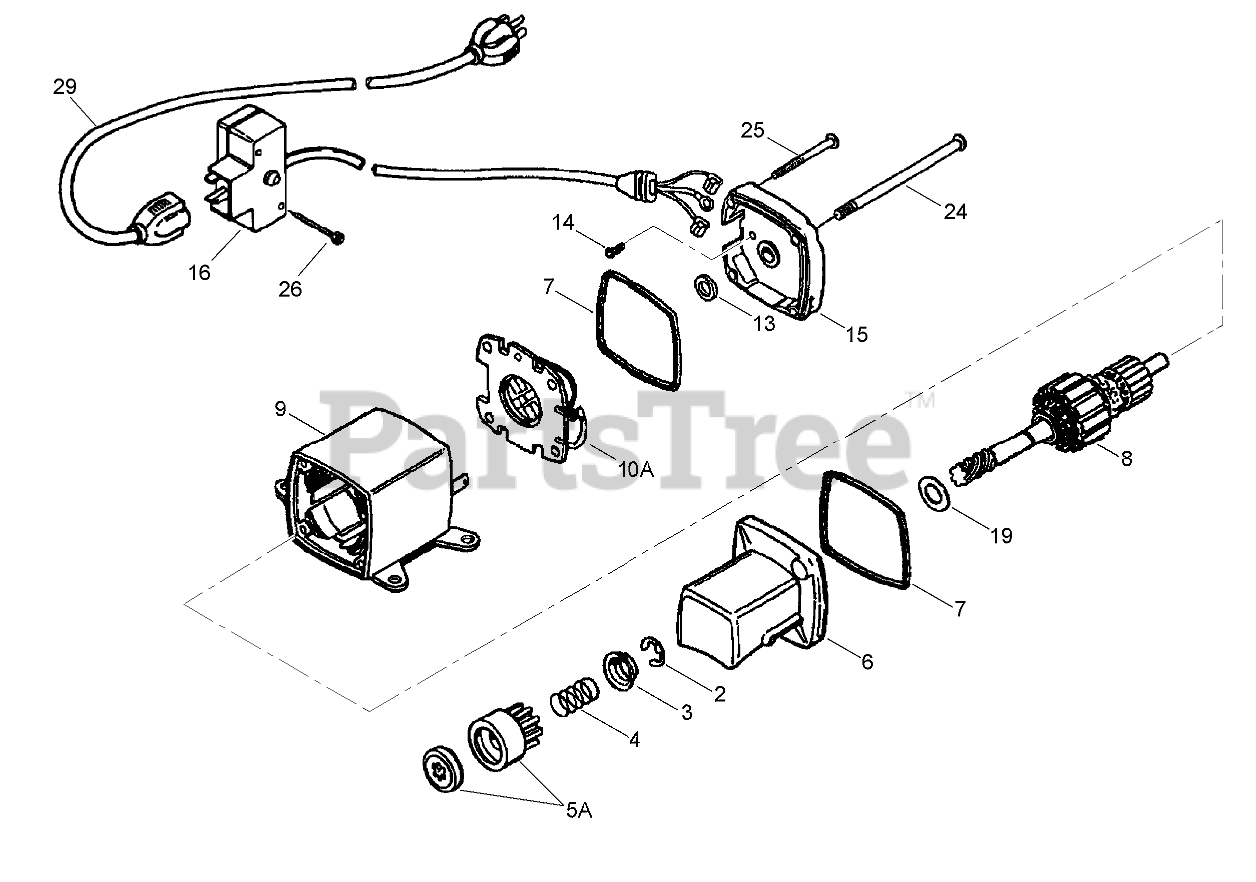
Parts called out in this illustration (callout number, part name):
2	Retainer-Ring
3	Retainer-Spring
4	Spring-Anti Drift
5A	Nut and Gear ASM (Includes 2)
6	Drive End Cap Asm (Includes 7)
7	O-Ring
8	Armature
9	Housing Asm (Must Purchase Complete Motor)
10A	Brush Card ASM
13	Washer-Thrust
14	Screw-Ground
15	Commutator End Cap ASM
16	Switch Box Asm
19	Washer-Thrust
24	Bolt-Case
25	Screw-Ground
26	Screw (O.E.M. supplied)
29	Cord-Extension (10-6) (Ref to engine parts list for mtg hardware)
